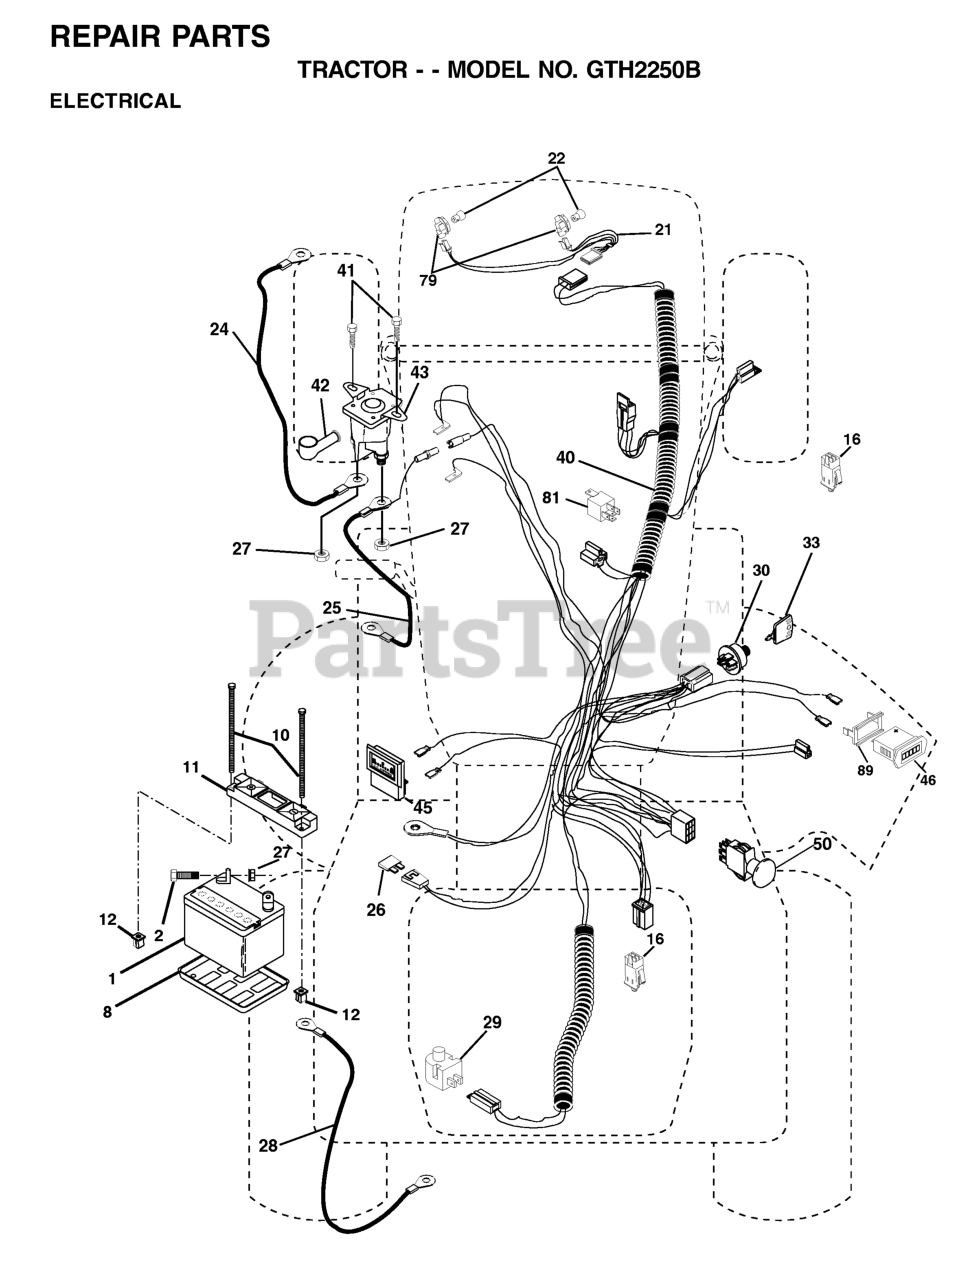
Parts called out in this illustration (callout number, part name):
1	BATTERY
2	BOLT.HEX.1/4.X.3/4.DICHROMATE
8	BATTERY TRAY T
10	BOLT 1/4-20 X 7.5
11	BATTERY HOLDDOWN FRONT MOUNT
12	NUT, PUSH NYLON 1/4" BATTERY
16	SWITCH INTERLOCK
21	HARNESS ASM LIGHT
24	CABLE-BATTERY YTV
25	CABLE, BATTERY
27	NUT
28	CABLE, GROUND
29	PLUNGER SWITCH (COLOR:OLIVE)
30	IGNITION SWITCH
33	KEY MLD GEN DELTA
40	HARNESS, IGNITION
41	SCREW
42	TERMINAL COVER
43	SOLENOID
46	HOUR METER
50	RP.PTO.SWITCH.8 TERMINAL.BLACK
79	BULBHOLDER ASM
81	RELAY.ASSY.T
89	BRACKET SNAP-IN HOURMETER
